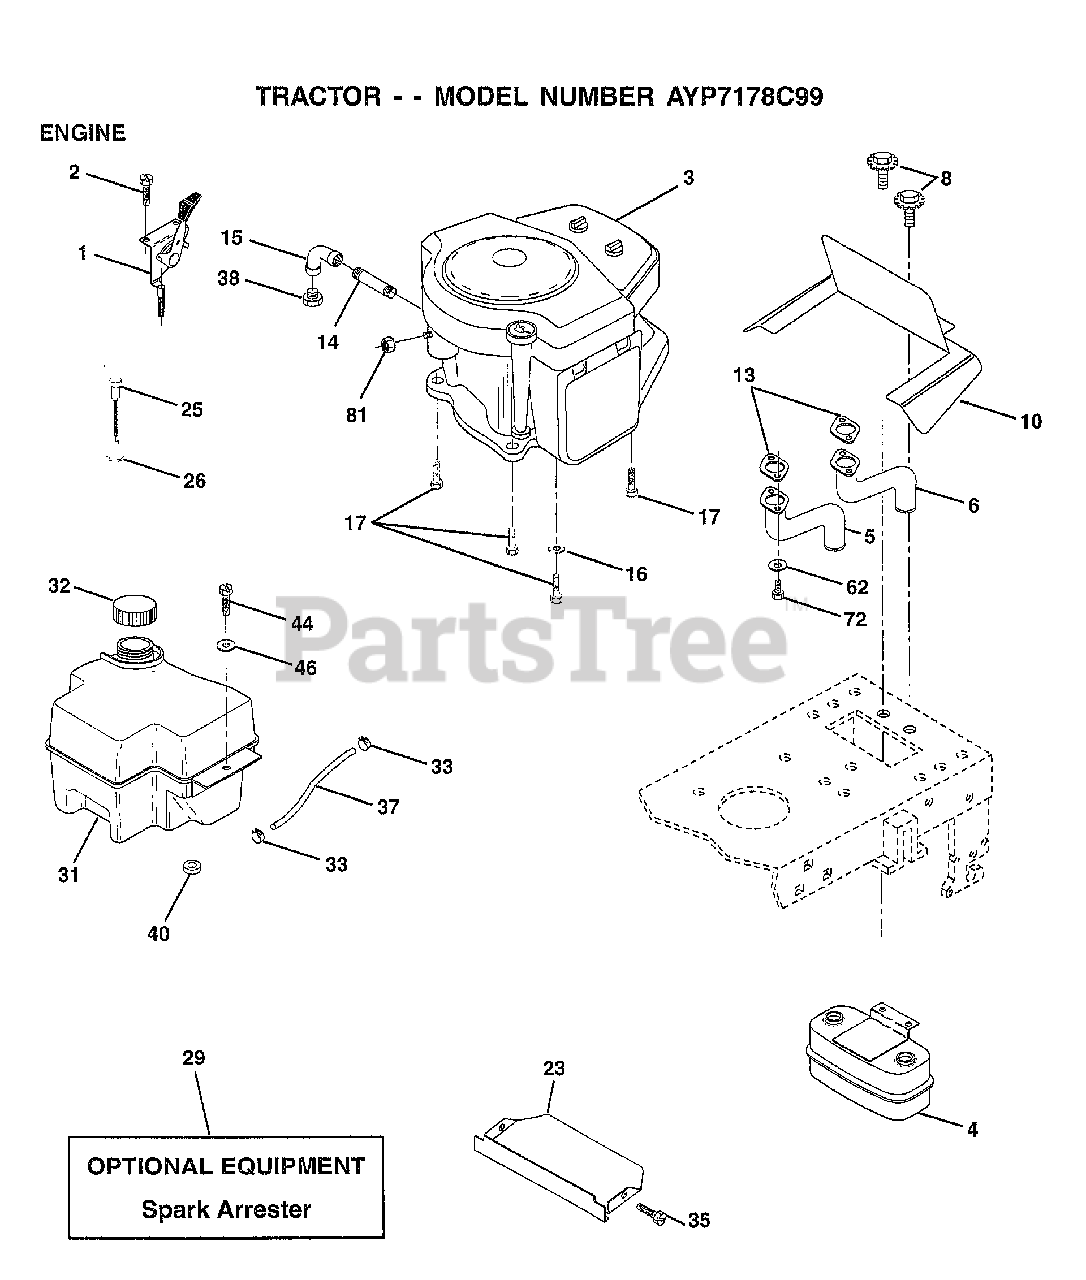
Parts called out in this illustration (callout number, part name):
1	CONTROL THROT. LH
2	SCREW LT
4	MUFFLER.TW.LOTONE
5	TUBE MANIFOLD LH
6	TUBE MANIFOLD RH
8	BOLT.5/16-18.UNC
10	SHIELD.BROWNING
14	PIPE NIPPLE LT
15	ELBOW
16	LOCKWASHER
17	SCREW LT
23	SHIELD.BRN/DBR.GD
25	CONTROL.CHOKE.37
26	"NUT,KEPS 3/8-24IM"
31	TANK.FUEL.FRONT.
32	CAP ASM FUEL
33	HOSE CLAMP
35	SCREW
37	LINE FUEL
44	SCREW HEX CRT
46	WASHER
62	LOCKWASHER
72	SCREW
81	NUT
